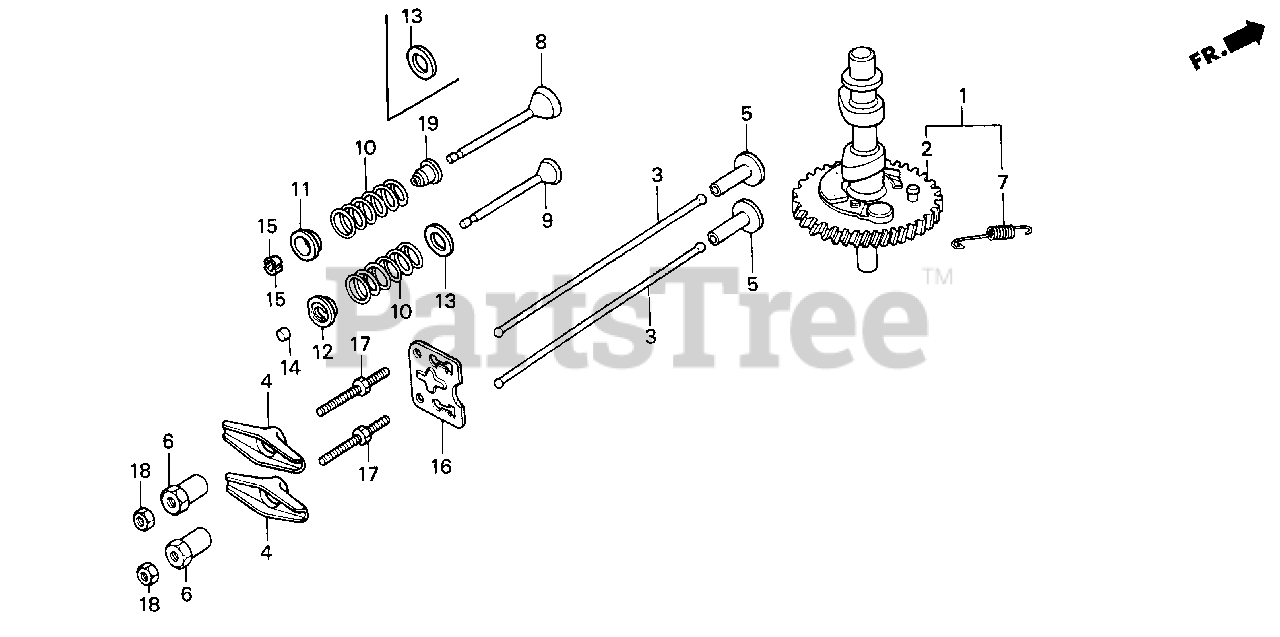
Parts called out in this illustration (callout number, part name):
3	ROD, PUSH
4	ARM, VALVE ROCKER
5	LIFTER, VALVE
6	PIVOT, ROCKER ARM
8	VALVE, IN.
9	VALVE, EX.
10	SPRING, VALVE
11	RETAINER, VALVE SPRING
12	RETAINER, EX. VALVE SPRING
13	SEAT, VALVE SPRING
14	ROTATOR, VALVE
15	COTTER, VALVE (SANKO)
16	PLATE, PUSH ROD GUIDE
17	BOLT, PIVOT (8MM)
18	NUT, PIVOT ADJ.
19	SEAL, VALVE STEM
